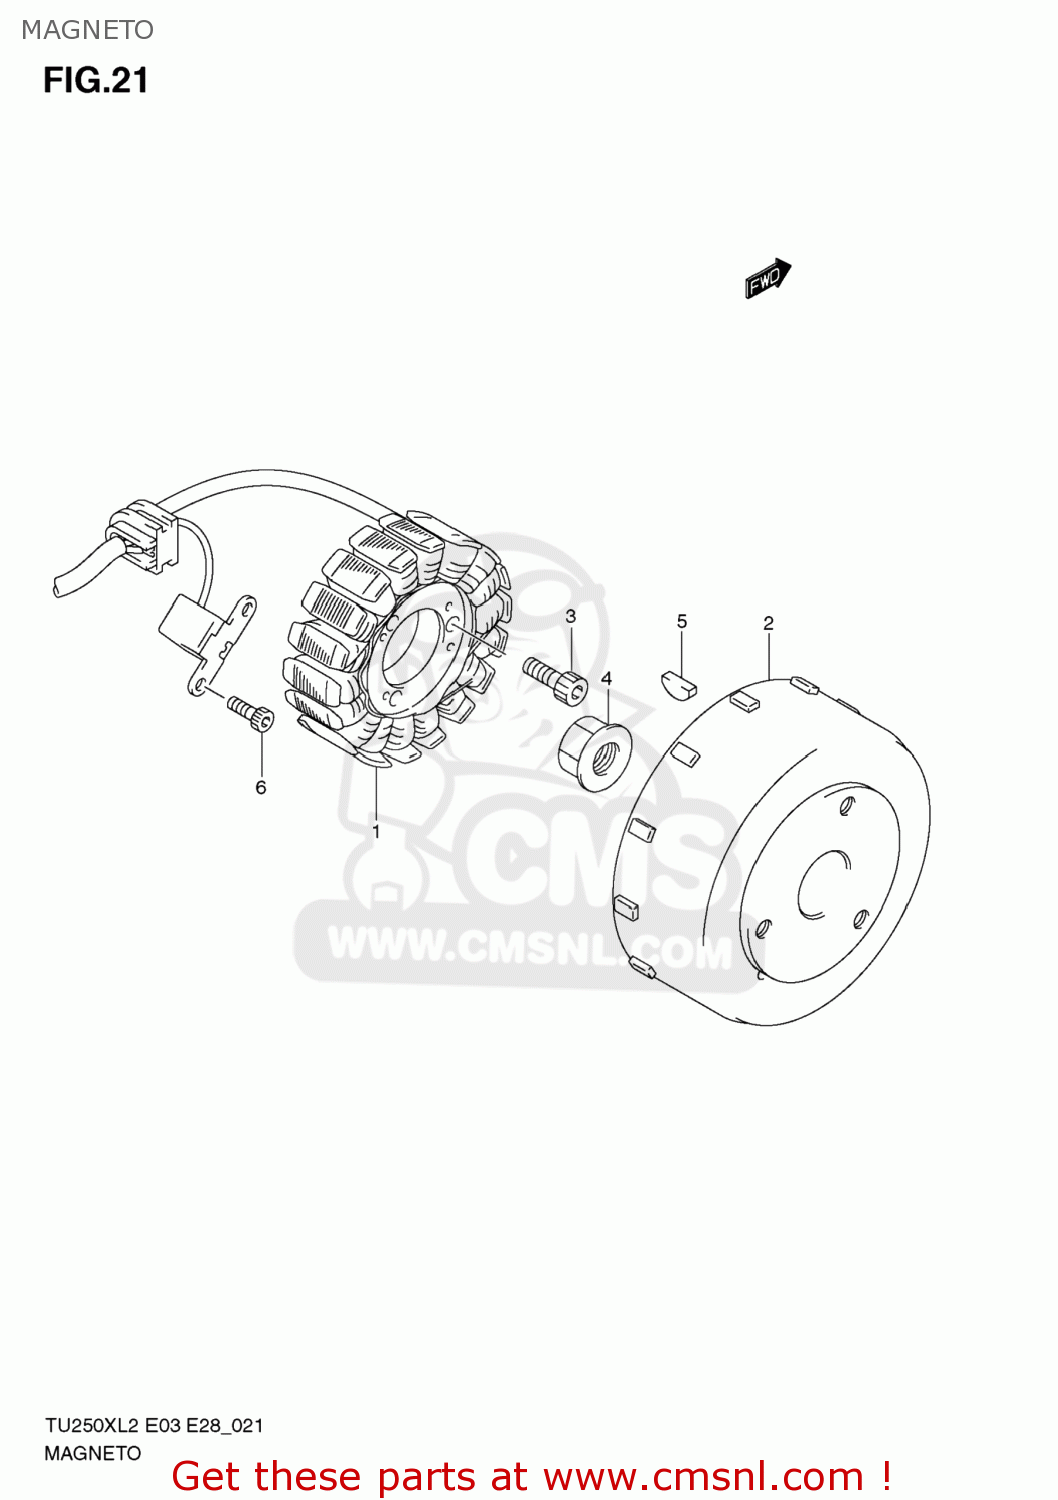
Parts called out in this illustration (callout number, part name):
1	STARTER ASSY
2	ROTOR ASSY
3	BOLT
4	NUT,GENERATOR ROTOR
5	KEY
6	BOLT
